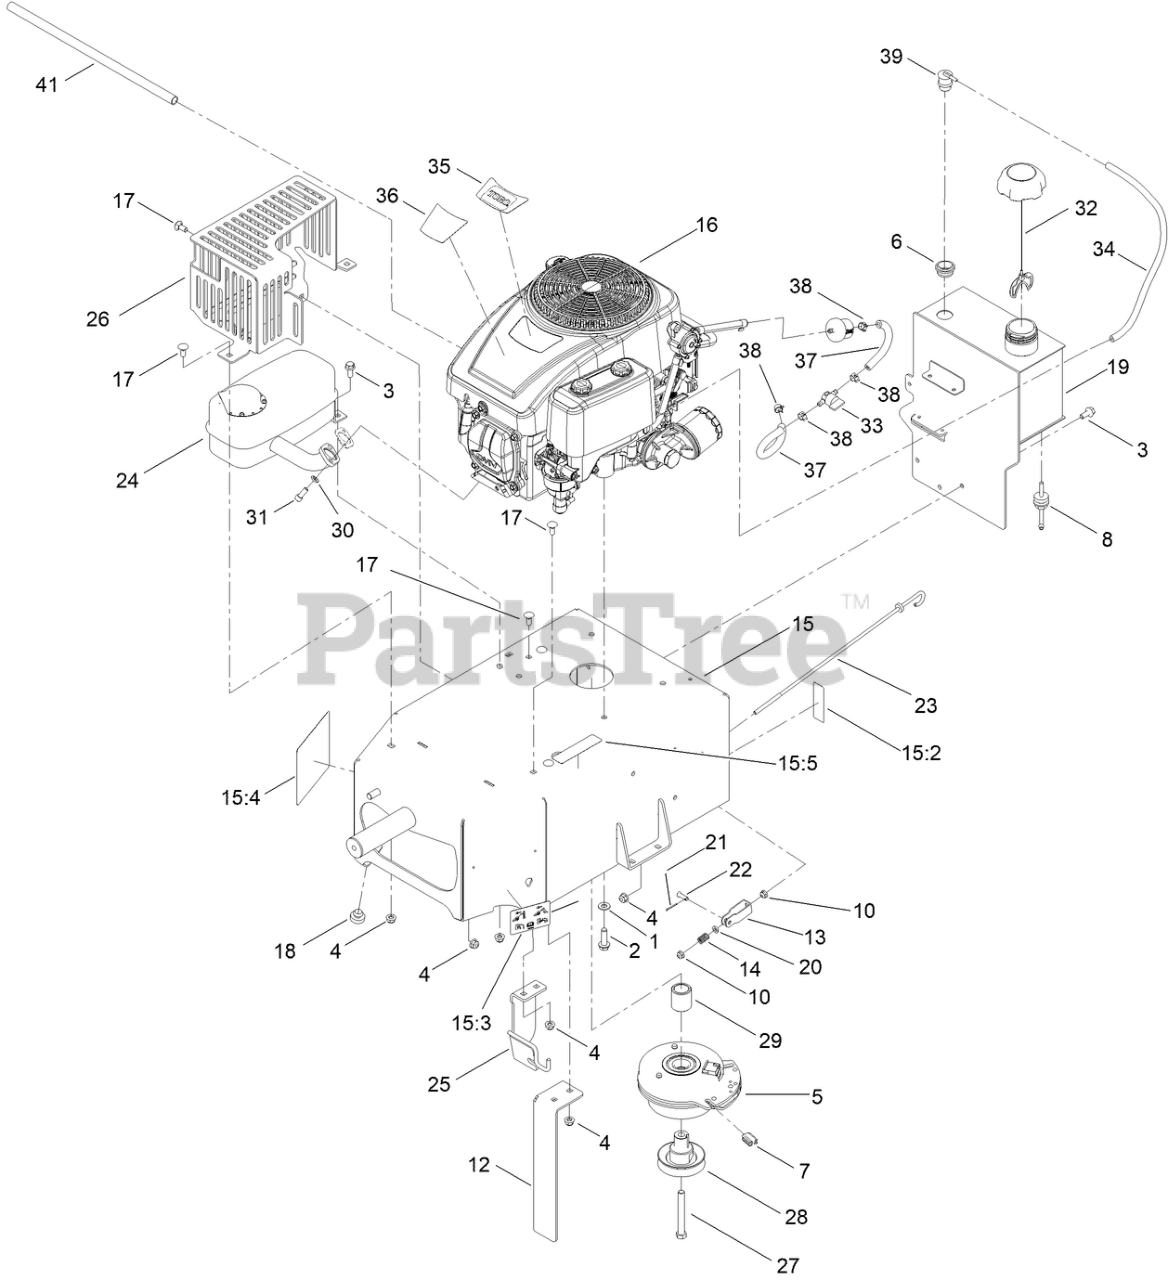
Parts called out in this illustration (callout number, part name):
1	WASHER-FLAT
2	SCREW-THD
3	SCREW-HHF
4	NUT-HF, NI
5	CLUTCH-ELECTRIC
6	GROMMET
7	ISOLATOR-CLUTCH
8	FITTING-FUEL, BULKHEAD
10	NUT-HF
12	BRACKET-TORQUE
13	CLEVIS
14	SPRING-COMPRESSION
15	FRAME ASM
15:2	DECAL-BRAKE, PARKING
15:3	DECAL-BYPASS
15:4	DECAL-SERVICE
15:5	DECAL-ARRESTOR, SPARK
16	KIT-ENGINE, SVC LC1P92F-1
17	BOLT-CARR
18	BUMPER-RUBBER
19	TANK-FUEL
20	SPACER-PLATE, PIVOT
21	PIN-COTTER
22	PIN-CLEVIS
23	ROD-BRAKE
24	MUFFLER
25	GUIDE-BELT/CABLE
26	GUARD-MUFFLER
27	SCREW-HH
28	PULLEY-HYDRO
29	SPACER-CLUTCH
30	WASHER-LOCK
31	SCREW-HSH
32	CAP-FUEL
33	VALVE-FUEL
34	HOSE-FUEL
35	DECAL-ENGINE
36	DECAL-DISPLACEMENT, ENGINE
37	HOSE-FUEL
38	CLAMP-HOSE
39	VALVE-VENT, FUEL
41	TUBE-DRAIN, OIL
